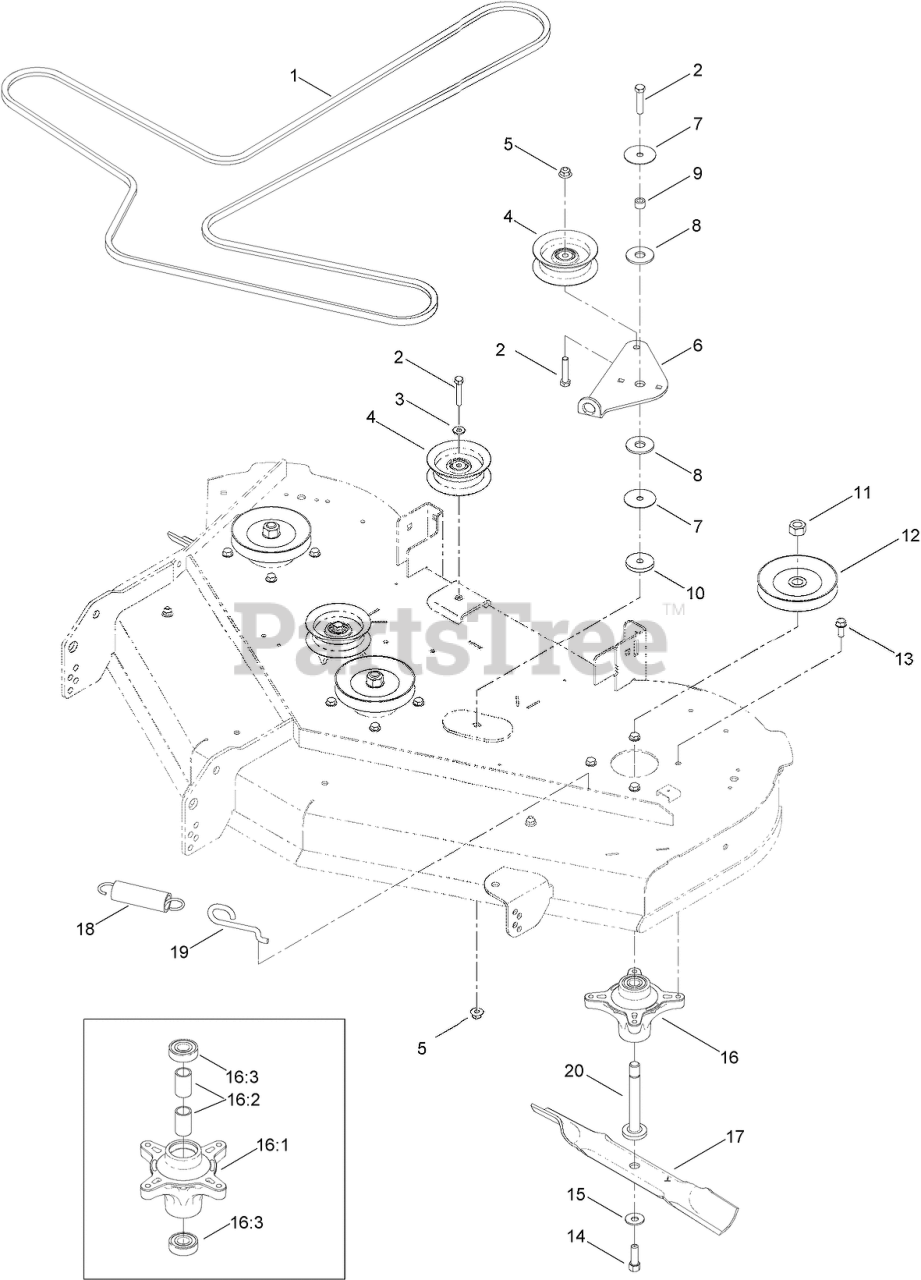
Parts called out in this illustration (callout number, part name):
1	V-BELT
2	SCREW-HH
3	WASHER-FLAT
4	PULLEY-IDLER, FLAT
5	NUT-HF, NI
6	ARM-IDLER
7	WASHER
8	WASHER-FRICTION, COMPOSITE
9	SPACER
10	SCREW-HH
11	NUT-HEX
12	PULLEY
13	SCREW-TAPTITE
14	SCREW-HH
15	WASHER-BELLEVILLE
16	SPINDLE ASM
16:1	SPINDLE
16:2	SPACER
16:3	BEARING-BALL
17	BLADE-HI LIFT
18	SPRING-EXTENSION
19	HOOK-RETURN, SPRING
20	SHAFT-SPINDLE
